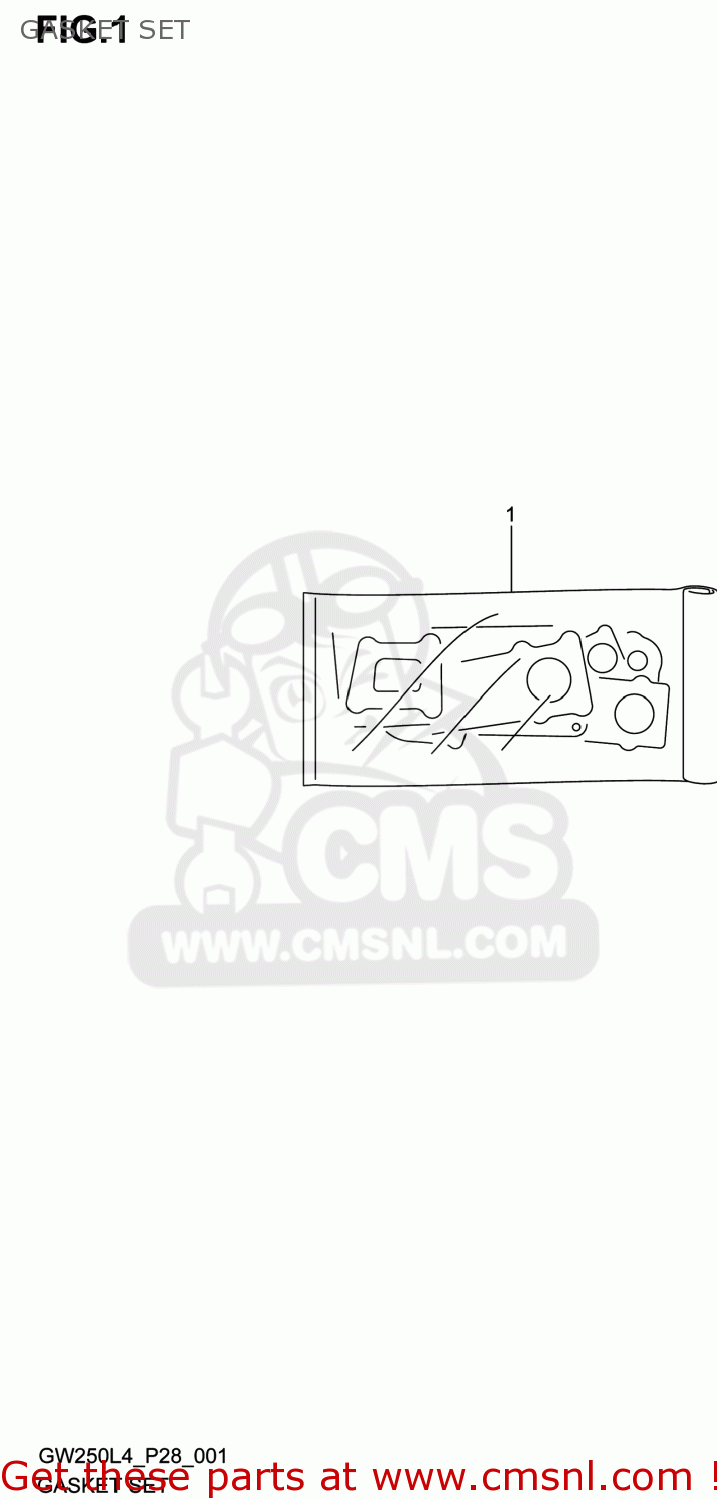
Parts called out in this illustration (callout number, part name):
1	GASKET SET (NAS)
2	GASKET,CYLINDER HEAD (NAS)
3	GASKET,CYL HEAD COVER (NAS)
4	WASHER,CYL HEAD COVER
5	GASKET,CYLINDER (NAS)
6	GASKET,BREATHER COVER(NA) (NAS)
7	GASKET,CLUTCH COVER (NAS)
8	GASKET,MAGNETO COVER (NAS)
9	GASKET,OIL PAN(ASB) (NAS)
10	GASKET,TENSIONER ADJUSTER(NA) (NAS)
11	GASKET,EXHAUST PIPE (NAS)
12	O RING(D:3.1,ID:32.7)
